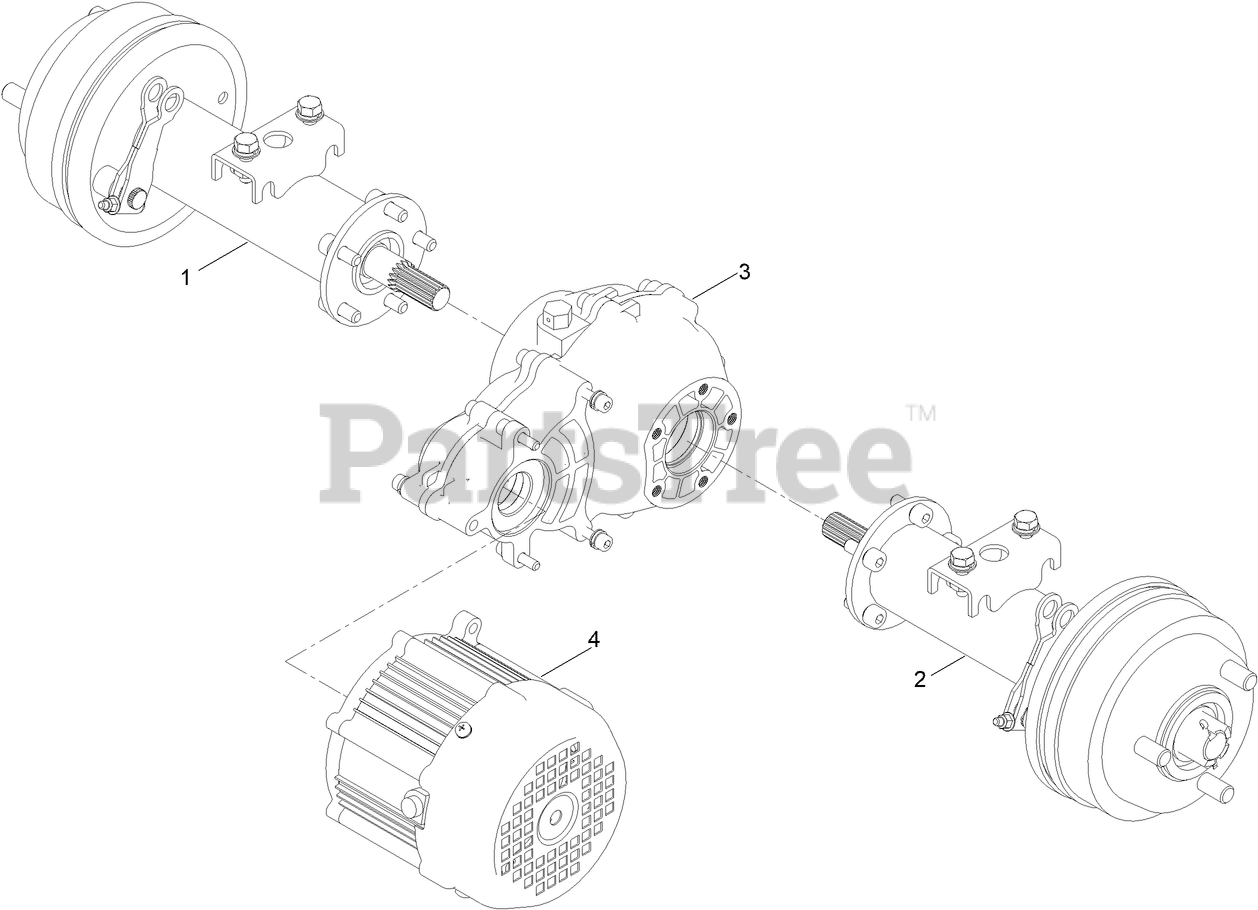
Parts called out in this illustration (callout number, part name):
1	SEMI AXLE ASM
2	SEMI AXLE ASM
3	REDUCTION GEARBOX ASM
4	REAR MOTOR ASM
